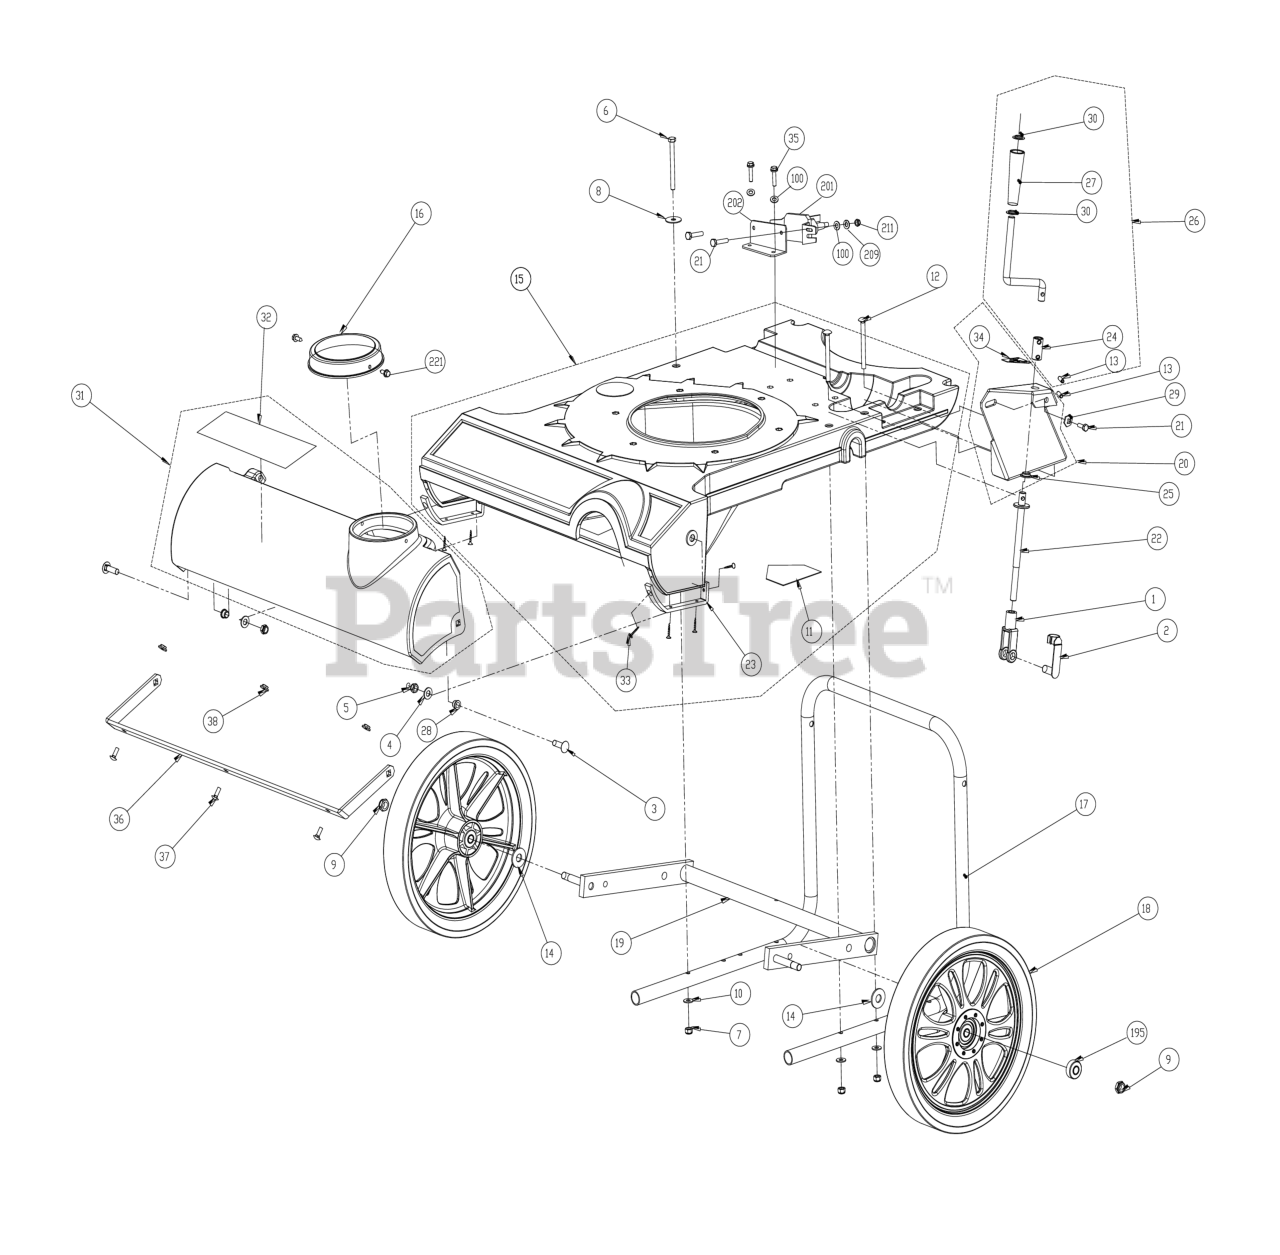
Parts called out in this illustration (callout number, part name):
1	YOKE 1/2"-20
2	PIN YOKE 1/2"
3	SCREWCAP BUTTON HEAD, 3/8-16 X 1 1/4" PL
4	WASHER 3/8"SAE 13/32"X13/16"X1/16"
5	NUT LOCK 3/8-16 LT WT THIN ZP
6	SCREWCAP 5/16"-18X3 1/2" HCS ZP
7	NUT LOCK 5/16"-18 HEX Z/P
8	WASHER FLAT FENDER 5/16
9	NUT LOCK 1/2"-13 NYLON INSERT
10	WASHER 1/4" FLAT Z/P
11	LABEL WARNING OPEI
12	BOLT CARRIAGE 5/16"-18 X 3 1/2" ZP
13	PIN ROLL 1/4" X 1"
14	WASHER 1/2" SAE Z/P
15	NOZZLE MV VAC ASSEMBLY
16	PLUG HOSE 5" VAC
17	HANDLE LOWER BRACE MV
18	WHEEL AND TIRE 14" SMOOTH
19	AXLE FRONT WA VAC
20	BRACKET HGT ADJ WA WA/LABEL MV VAC
21	SCREWCAP 1/4"-20X3/4" HCS ZP
22	LINK HGT ADJ SP VAC
23	BRACKET NOZZLE WEAR GUARD VAC
24	ROD CONNECT HGT ADJ
25	BUSHING 0.5 ID 0.625 OD X 0.25
26	ROD HANDLE CRANK ASSEMBLY
27	HANDLE CRANK
28	BUSHING 3/8 ID X 1/2 OD X 3/8
29	WASHER LOCK 1/4" TWISTED TOOTH
30	INTERNAL TOOTH WASHER BRASS
31	NOZZLE COVER MV VAC ASSY
32	LABEL BADGING MV
33	SCREW SHEETROCK 1" LONG
34	LABEL HGT ADJ MV VAC
36	BRACKET NOZZLE COVER REINFORCE
37	BOLT CARRIAGE 1/4" X 3/4"
38	NUT WHIZ 1/4"-20 WASH FACE
195	BEARING 1/2 ID
221	SCREW PLASTITE 1/4-10 X 3/4 HWH ZP
